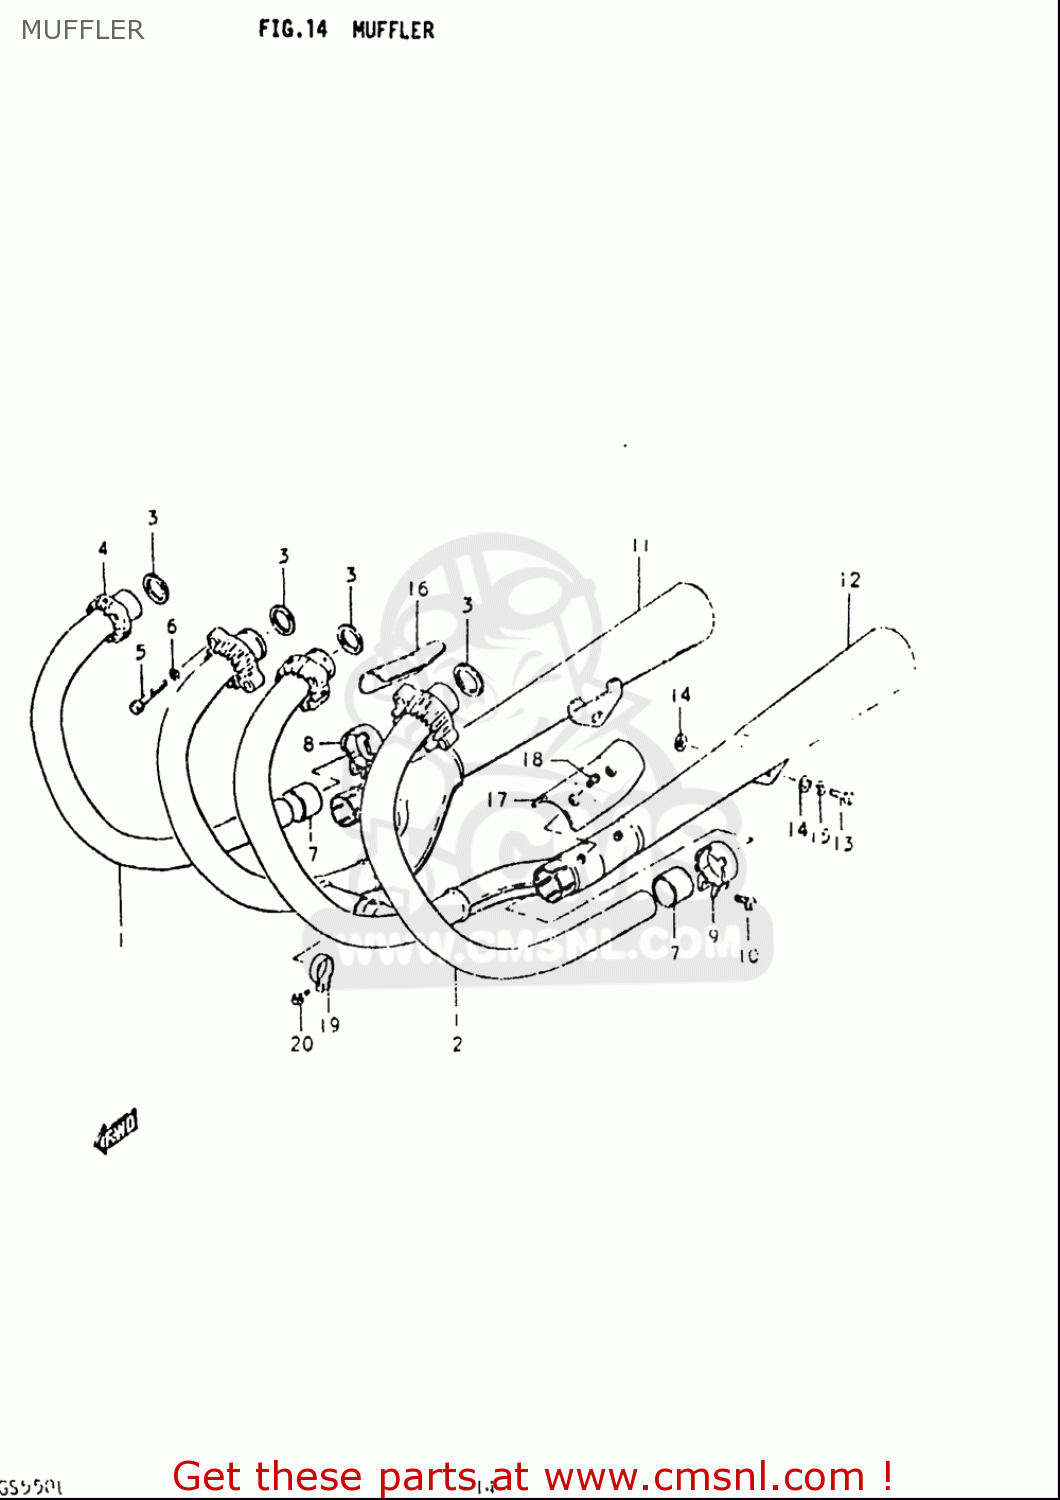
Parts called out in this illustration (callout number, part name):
1	PIPE,EXHAUST,RIGHT
3	GASKET,EXHAUST PIPE (NAS)
4	CLAMP,EXHAUST PIPE
5	BOLT
6	WASHER,LOCK
7	CONNECTOR,MUFFLER
8	CLAMP,MUFFLER CONNECTOR,R
9	CLAMP,MUFFLER CONNECTOR,L
10	BOLT
13	BOLT
14	WASHER
15	WASHER,LOCK
16	COVER,MUFFLER,RIGHT
17	COVER,MUFFLER,LEFT
18	SCREW(5X6)
20	BOLT
